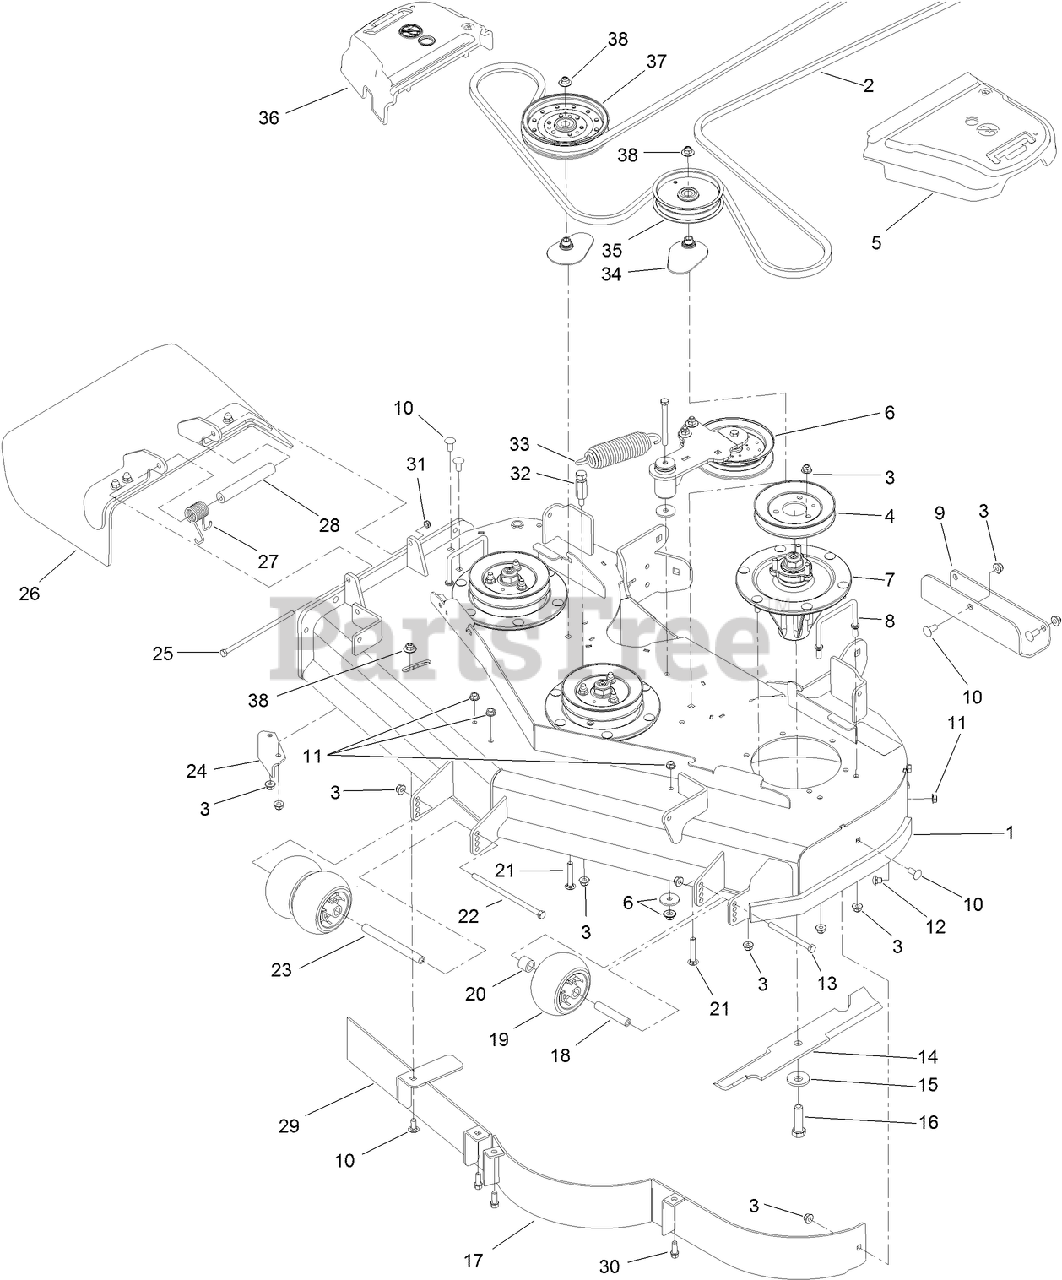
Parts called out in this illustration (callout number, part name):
1	DECK DECAL ASM
2	BELT-V
3	NUT-HF, NI
4	PULLEY
5	COVER-BELT, LH
6	IDLER ARM ASM
7	SPINDLE ASM
8	WIREFORM-COVER
9	PLATE-SKID
10	SCREW-CARR
11	NUT-HHF, WHIZ
12	SCREW-CARR
13	SCREW-HH
14	BLADE-16.5 INCH (HIGH FLOW)
15	Washer-Blade Bolt, Heavy
16	SCREW-BLADE
18	TUBE-SPANNER
19	ROLLER-SCALP, ANTI
20	TUBE-SPACER
21	BOLT-CARR, SHORT NECK
22	SCREW-HH
23	SPACER-WHEEL
24	BAFFLE-DISCHARGE
25	SCREW-HH
26	RUBBER DEFLECTOR ASM
27	SPRING-TORSION
28	SPACER
29	BAFFLE ASM
30	SCREW-HWH
31	NUT-LOCK, NI
32	ANCHOR-SPRING, TALL
33	SPRING-EXTENSION
34	SPACER-PULLEY
35	PULLEY-IDLER, FLAT
36	COVER-BELT, RH
37	PULLEY-IDLER, FLAT
38	NUT-FLANGE, NI
